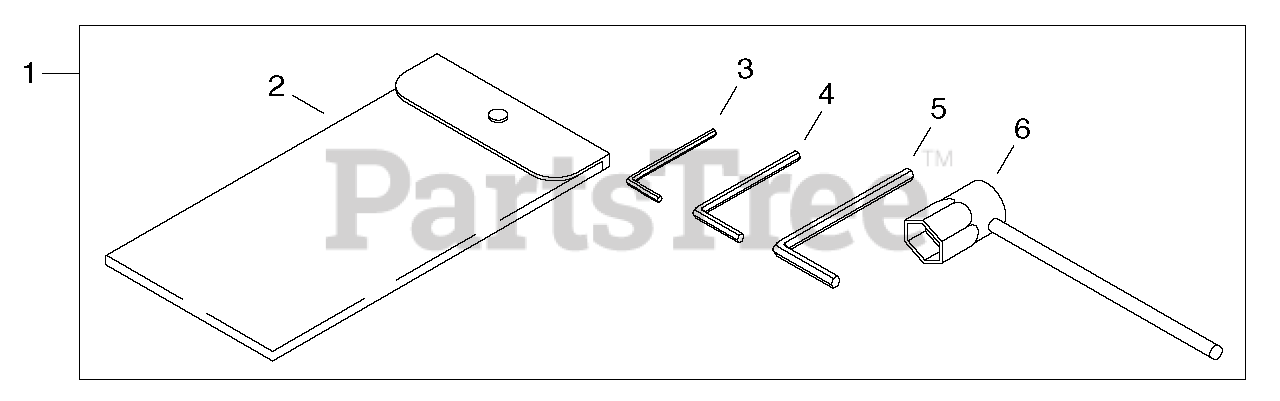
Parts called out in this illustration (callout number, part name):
1	TOOL KIT
2	BAG, TOOL
3	HEX KEY - 3mm
4	HEX KEY - 4mm
5	HEX KEY - 6mm
6	T-WRENCH - 19mm
